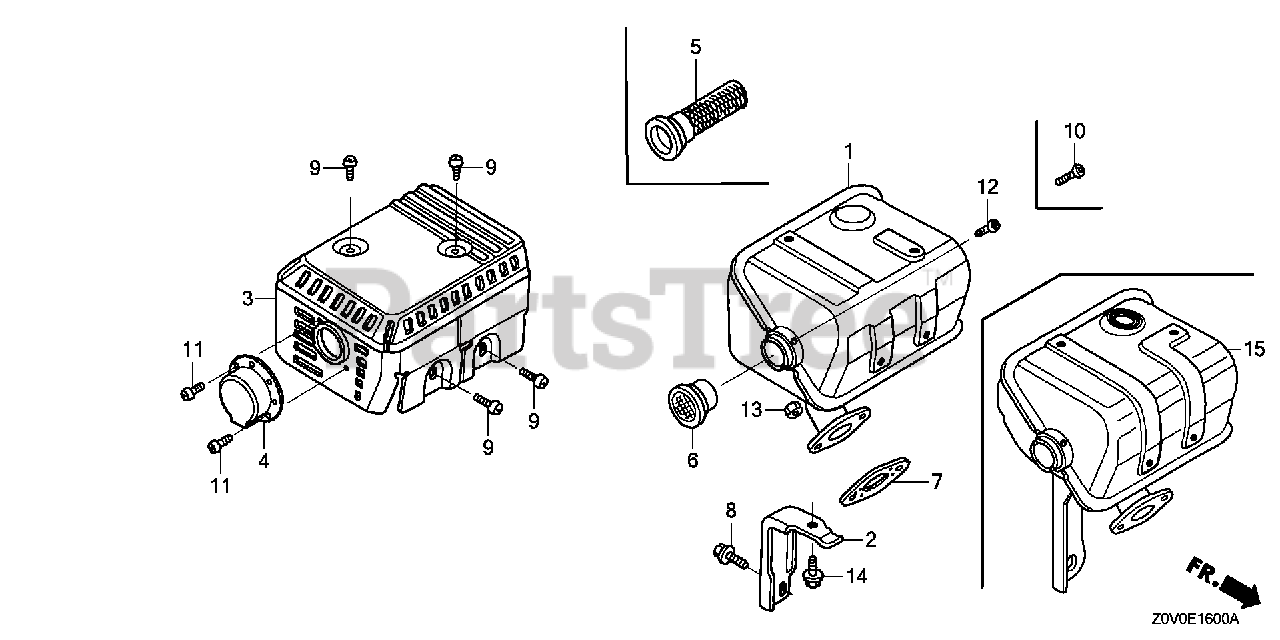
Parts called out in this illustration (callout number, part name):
2	STAY, MUFFLER
3	PROTECTOR, MUFFLER (SILENT)
5	ARRESTER, SPARK
6	NETTING, WIRE FLANGE
7	GASKET, MUFFLER
8	BOLT, FLANGE (6X13) (CT200)
9	SCREW, TAPPING (5X8)
10	SCREW, TAPPING (4X6)
12	SCREW, TAPPING (4X6)
13	NUT, HEX. (8MM)
14	BOLT, FLANGE (6X12)
